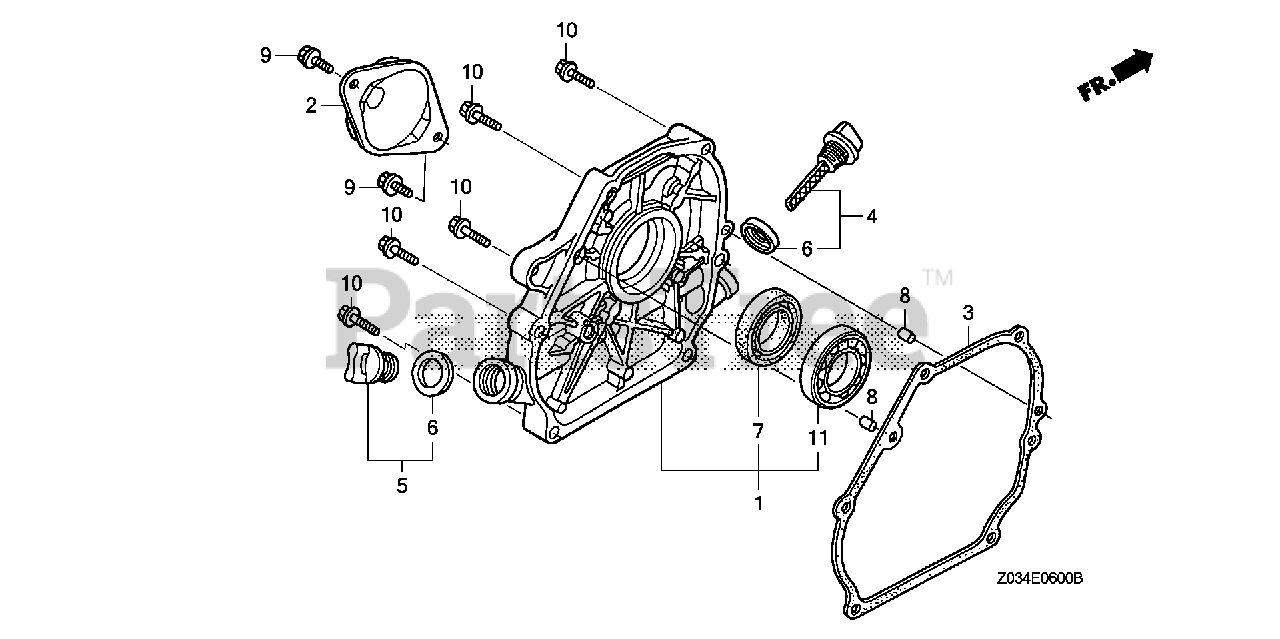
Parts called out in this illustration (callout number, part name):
1	COVER ASSY., CRANKCASE
2	GUARD, SHAFT
3	GASKET, CASE COVER
4	CAP ASSY., OIL FILLER (GRAY)
5	CAP ASSY., OIL FILLER
6	GASKET, OIL FILLER CAP
7	OIL SEAL (25X41X6) (NOK)
7	OIL SEAL (25X41X6)
8	PIN, DOWEL (8X14)
9	BOLT, FLANGE (8X16)
10	BOLT, FLANGE (8X32)
11	BEARING, RADIAL BALL (6205)
